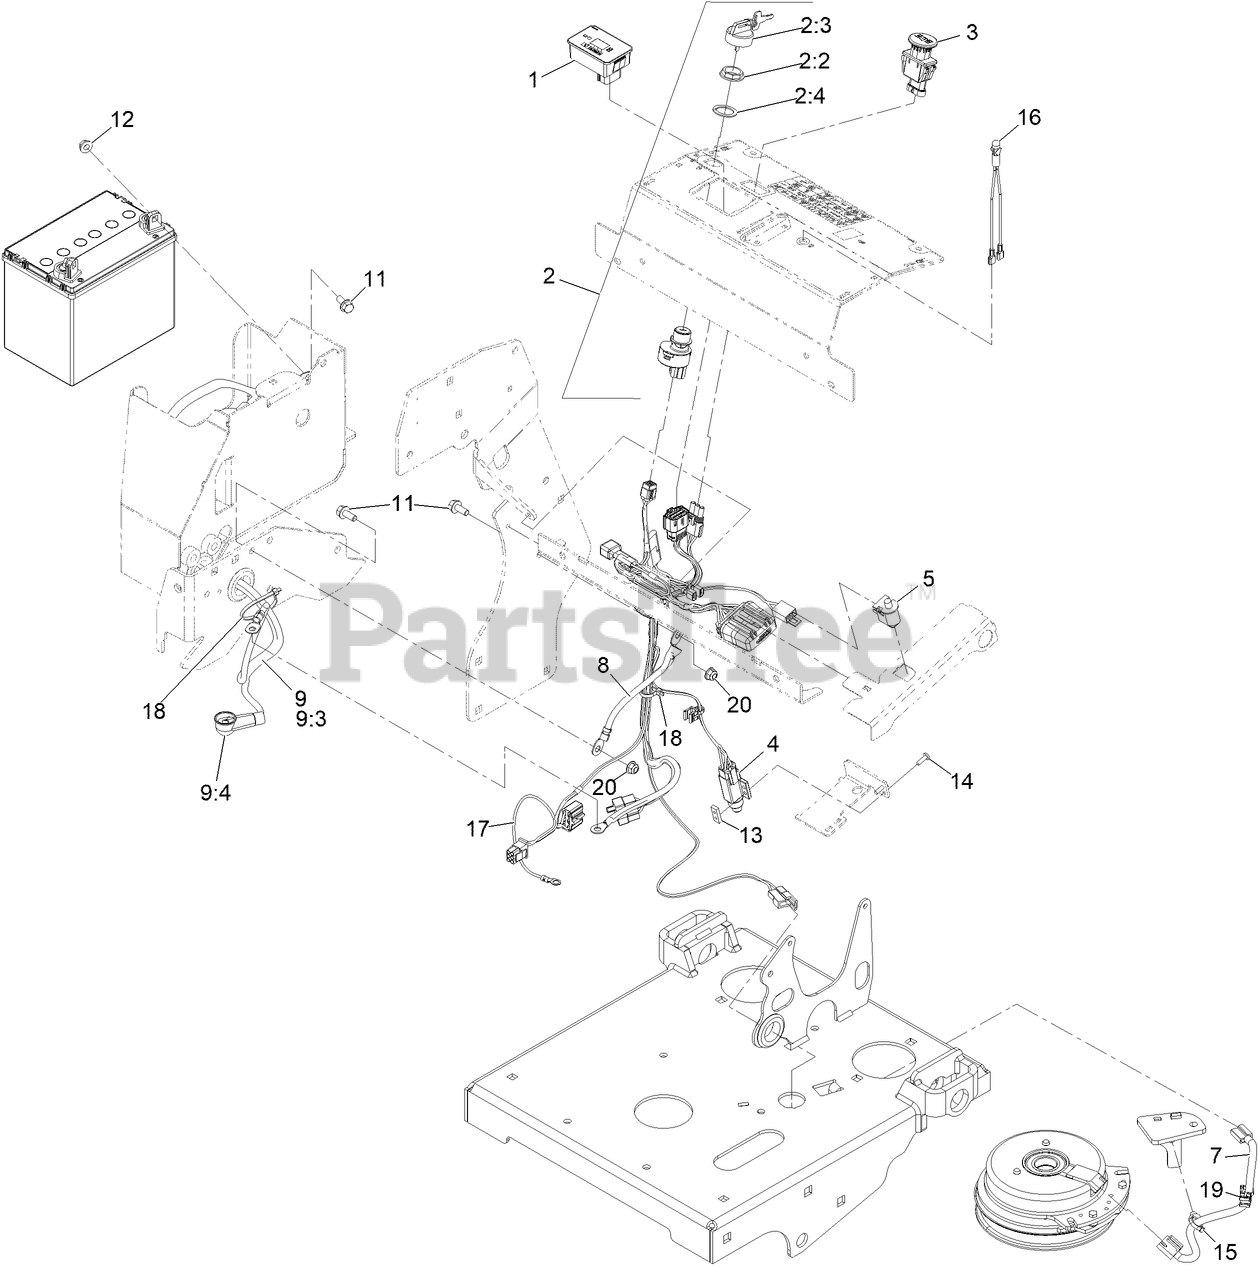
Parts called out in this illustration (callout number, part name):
1	MODULE-HOUR METER
2	IGNITION SWITCH ASM
2:2	NUT-MOUNTING
2:3	IGNITION KEY SET
2:4	WASHER-BACKUP
3	SWITCH-PTO, SEALED
5	SWITCH-BAIL
7	HARNESS-CLUTCH PIGTAIL
8	HARNESS-WIRING
9	HARNESS-BATTERY
9:3	Insulator-Lug, Red
9:4	Boot-Battery, Red
11	SCREW-HHF
13	PLATE-TAPPED
14	SCREW-PPH
15	CLIP-TIE
16	INDICATOR-LED, RED
17	Harness-Indicator Light, EFI
18	TIE-CABLE
19	Clip-Edge
20	NUT-HF, NI
